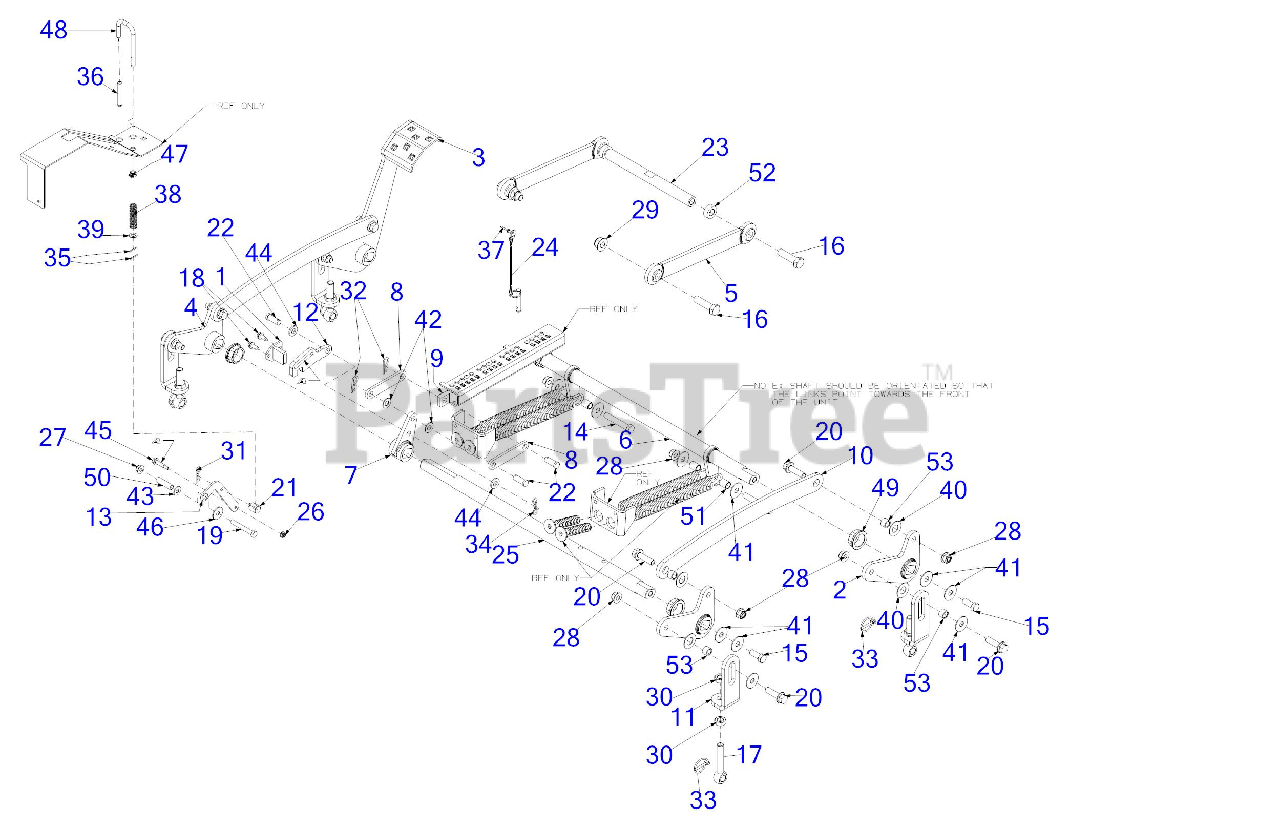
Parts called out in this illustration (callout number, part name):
6	FRONT DECK LIFT SHAFT
7	DECK LIFT HUB ASSEMBLY (LH)
8	DECK LIFT INDEX LINK
9	LIFT INDEX SLIDER ARM
13	PIVOT LOCKOUT LINK
14	SCREW-HEX 1/2-13 X 3.00
15	SCREW 1/2-13 x 1.25 GR5
16	SCREW 5/8-11 x 2.25 GR5
17	EYE BOLT 5/8-11 X 3.63
18	SCREW 5/16-18 x .750
19	SCREW 3/8-16 x 2.75 GR5
20	FLANGE BOLT 1/2-13:1.75:GR5
21	BRAKE FERRULE
22	CLEVIS PIN .500 x 1.25
23	FRONT LIFT SHAFT
24	DETENT PIN
25	LIFT SHAFT 1.25 DIA
26	FLANGE LOCK NUT
29	FLANGE LOCK NUT
30	HEX NUT
31	INTERNAL COTTER PIN
32	COTTER PIN
34	PIN:COTTER
35	COTTER PIN 3/32
37	FULL TUBULAR RIVET
38	COMPRESSION SPRING .656 ODX 2.445"
39	FLAT WASHER
40	FLAT WASHER .760ID X1.49OD x .06
41	WASHER .51 x 1.5 x .07
42	FLAT WASHER .510 x 1.00 x .060
43	FLAT WASHER
44	FLAT WASHER .510 x 1.000 x .125
45	SHOULDER SCREW
46	SHOULDER SPACER
47	BUSHING .380 ID
48	DECK LOCK OUT ROD
49	FLANGE BEARING
51	SPACER 0.535 X 0.68 X 0.83
